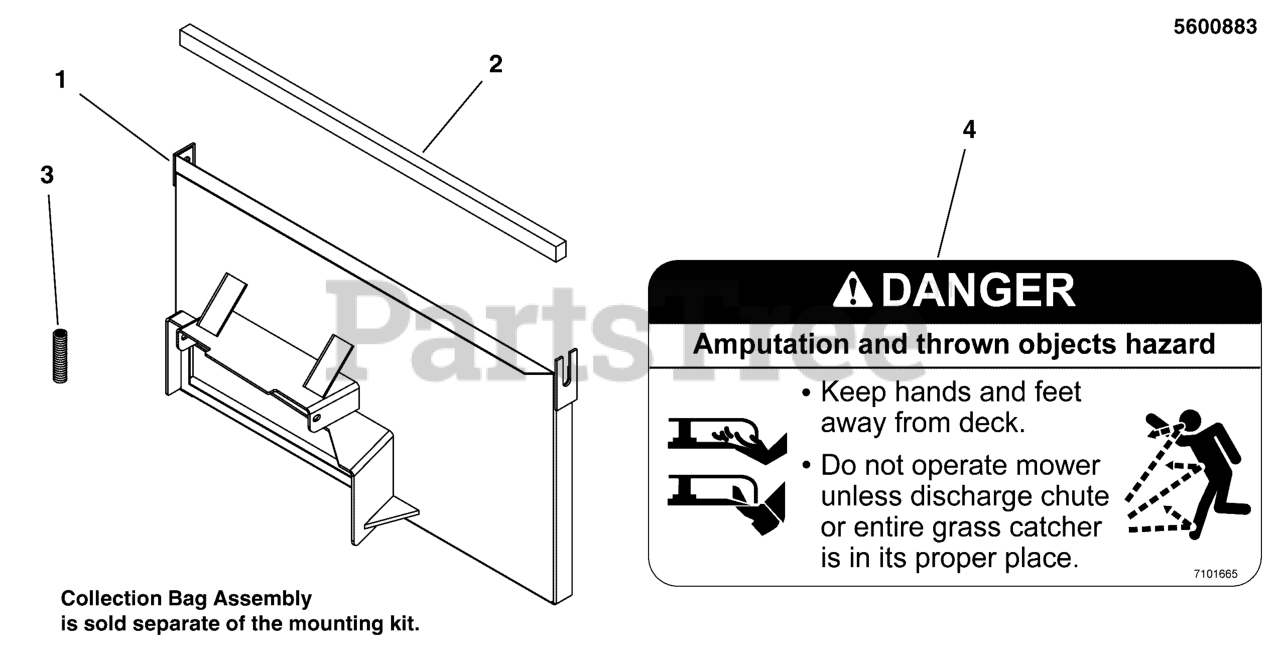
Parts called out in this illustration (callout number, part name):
1	WELD, BAGGER MOUNT, 36 - BLK
2	FOAM, 3/4 X 1 X 28.25
3	SPRING-COMP, .496ID X 3.00LG X .112WR
4	DECAL, DANGER DO NOT OPERATE W/O DEFLECT
